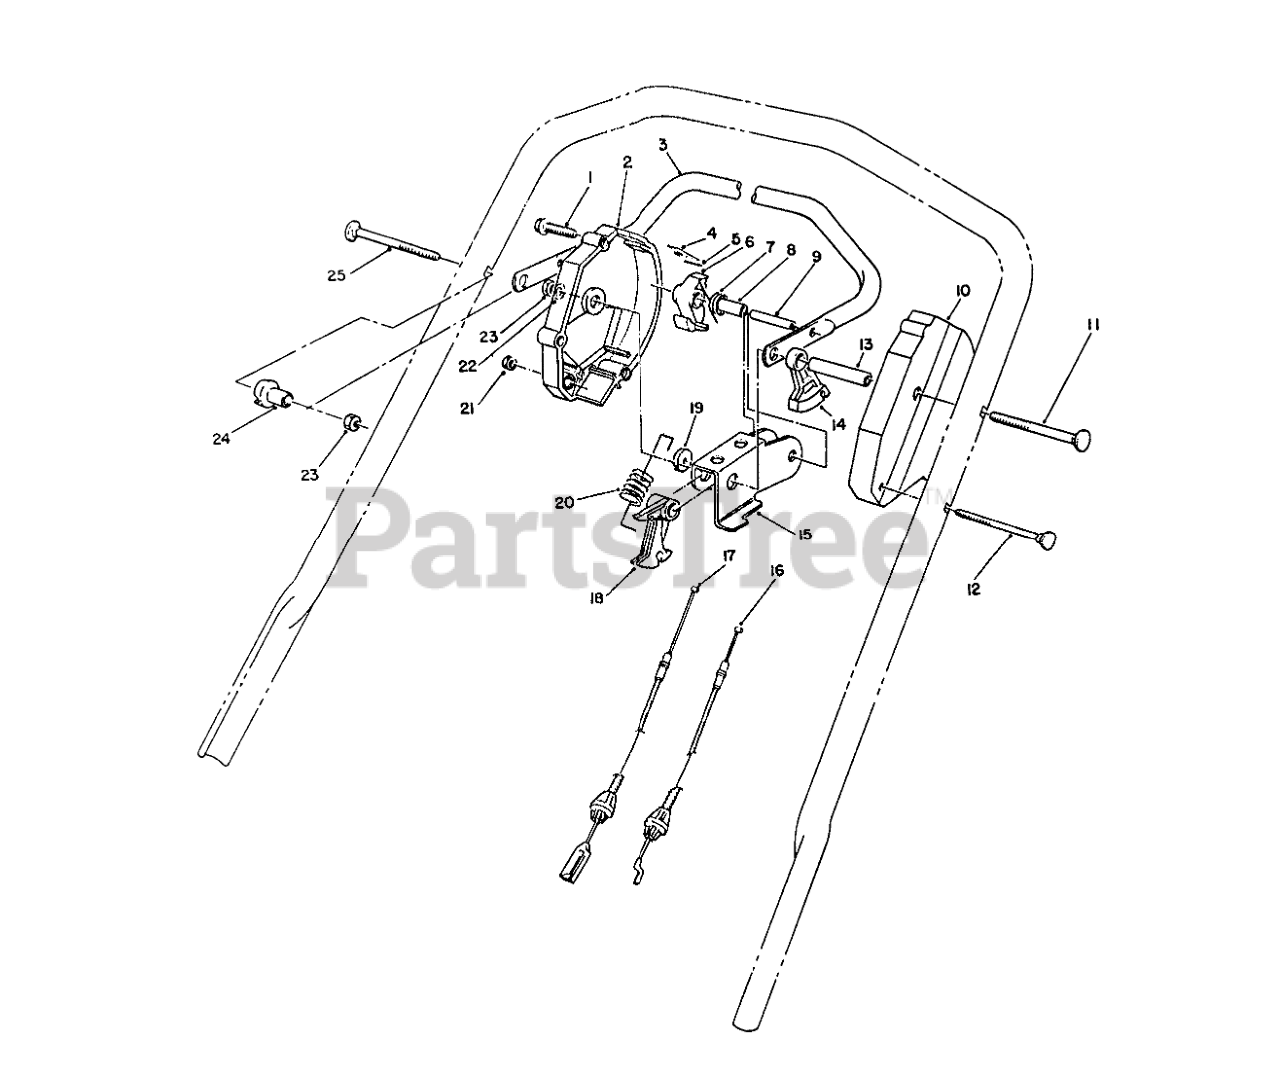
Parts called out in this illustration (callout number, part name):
1	SCREW-HWHTF
2	Housing-Control
3	Bar-Control
4	SPRING-LEAF
5	PIN-INSERT
6	HOOK-CONTROL
7	SPRING-TORSION
8	SPACER
9	PIN-ROLL, SLOTTED
10	HOUSING-CONTROL, LH
11	Screw-Handle
12	HANDLE SCREW
13	TUBING-SPACER
14	LEVER-TRACTION
15	ROCKER
16	TRACTION CABLE
17	BBC CABLE ASSEMBLY
18	LEVER-CABLE
19	WASHER-NYLON
20	SPRING-DETENT
21	NUT-HEX
22	WASHER-PLAIN
23	NUT-LOCK, NI
24	SPACER-SUPPORT
25	SCREW-HANDLE
